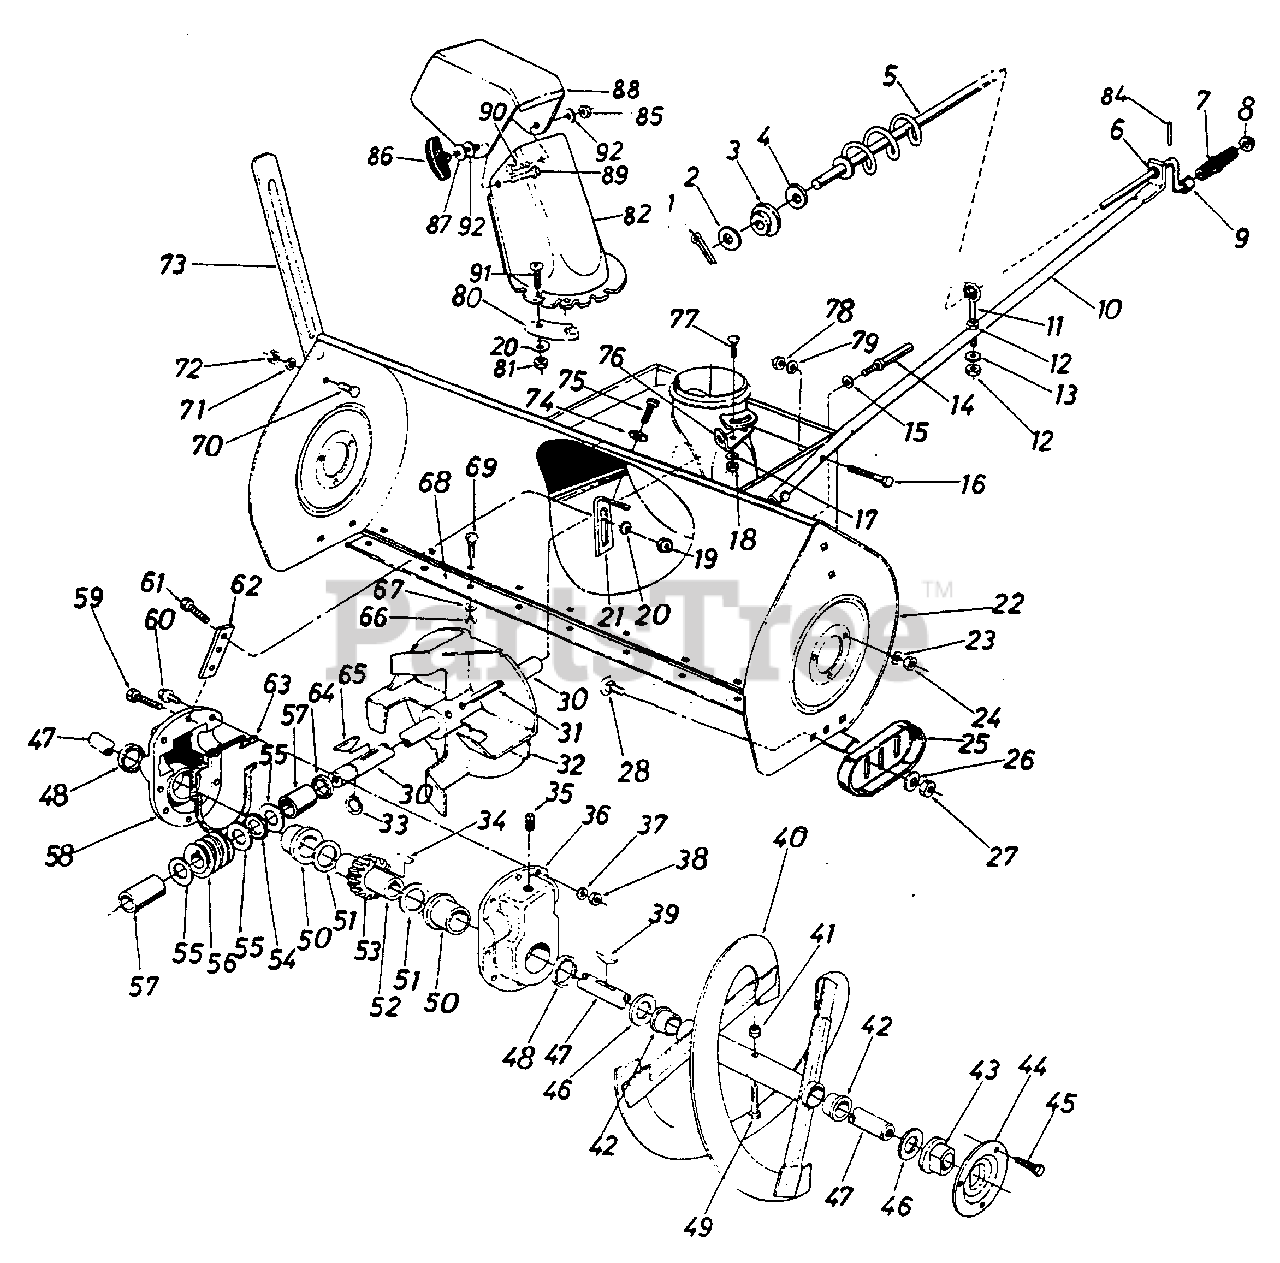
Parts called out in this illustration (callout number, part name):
1	Cotter Pin
2	Fl-Wash. .39" I.D. x .62" O.D.
3	Plastic Bushing
4	Fl-Wash. .385" I.D. x .62 O.D.
5	Chute Crank Ass'y.
6	Plastic Bushing
7	Knob (Black)
8	Push Nut 3/8" Rod
9	Spacer .385" I.D. x .50" O.D.
10	Chute Crank Support Tubing
11	Eyebolt
12	Hex Nut 5/16-18 Thd.
13	Bell-Wash. .345" I.D. x .88" O.D.
14	Stud 3/8-16 x 2.75" Lg.
15	Bell-Wash. .345" I.D. x .88" O.D.
16	Hex Bolt 3/8-24 x 1.25" Lg.
17	Bell-Wash. .345" I.D. x .88" O.D.
18	Hex Nut 5/16-18 Thd.
19	Hex Nut 1/4-28 Thd.
20	Bell-Wash. .265" I.D. x .75" O.D.
22	45" Snow Blower Housing Ass'y.
23	L-Wash. 5/16" I.D.
24	Hex Nut 5/16-18 Thd.
25	Slide Shoe
26	Bell-Wash. .400" I.D. x .88" O.D.
27	Hex Jam Nut 3/8-16 Thd.
28	Carriage Bolt 3/8-16 x .62" Lg.
30	Blower Axle .875" Dia. x 14.75" Lg.
31	Spring Pin Spir. 5/16" Dia. x 1.75" Lg.
34	#91 Woodr-Key 1/4 x 3/4" Dia. (Hdn.)
35	Vent Plug
36	Comp. Gear Hsg. Half-L.H.
37	Spr.-Wash. .32" I.D. x .62" O.D.
38	Hex Ins. L-Nut 5/16-18 Thd.
39	#91 Woodr-Key 1/4 x 3/4" Dia. (Hdn.)
41	Hex Ins. L-Nut 5/16-18 Thd.
42	Plastic Bushing
43	Flange Brg. w/flats 1" I.D.
44	Bearing Housing
45	Hex Sems Bolt 5/16-18 x .75" Lg.
46	Fl-Wash. 1.00" I.D. x 1.75" O.D.
47	Spiral Axle
48	Flange Bearing 1.503" I.D.
49	Shear Bolt 5/16-18 x 1.75" Lg.
50	Oil Seal 1.50" I.D.
51	Fl-Wash. 1.50" I.D. x 2.00" O.D.
52	Worm Gear Shaft
53	Double Threaded Worm Gear-L.H.
54	Thrust Brg.-.88" I.D. x 1.44" O.D.
55	Fl-Wash. .88" I.D. x 1.4" O.D.
56	Double Threaded Worm-L.H.
57	Sleeve
58	Complete Gear Hsg. Half-R.H.
59	Hex Bolt 5/16-18 x 1.25" Lg.
60	Hex Bolt 5/16-18 x 1.0" Lg. (Gr. 5)
61	Hex Bolt 1/4-28 x .75" Lg.
62	Gear Housing Support Plate
63	Rubber Gasket
64	Oil Seal-.875" I.D.
65	#9 Hi-Pro Key 3/16 x 3/4" Dia. (HT)
66	Hex Nut 5/16-18 Thd.
67	L-Wash. 5/16" I.D.
69	Carriage Bolt 5/16-18 x 1.00" Lg.
70	Carriage Bolt 5/16-18 x .62" Lg.
71	L-Wash. 5/16" I.D.
72	Hex Nut 5/16-18 Thd.
73	Guide Blade
74	Bell-Wash. .345" I.D. x .88" O.D.
75	Hex Wash. Hd. AB-Tap Scr. 5/16 x .75" Lg.
77	Carriage Bolt 5/16-18 x .75" Lg.
78	Hex Ins. L-Nut 3/8-24 Thd.
79	L-Wash. 3/8" I.D.
80	Chute Flange Keeper
81	Hex Nut 1/4-20 Thd.
82	Chute Ass'y. w/chute Guard
84	Bell-Wash. .345" I.D. x .88" O.D.
85	Hex Cent. L-Nut 5.16-18 Thd.
86	Knob Handle
87	Bell-Wash. .345" I.D. x .88" O.D.
88	Top Chute Ass'y.
89	Carriage Bolt 5/16-18 x 1.00" Lg.
90	Carriage Bolt 5/26-18 x .62" Lg.
91	Truss Mach. Scr. 1/4-20 x .75"
92	Roll Pin .12 Dia. x .63"
